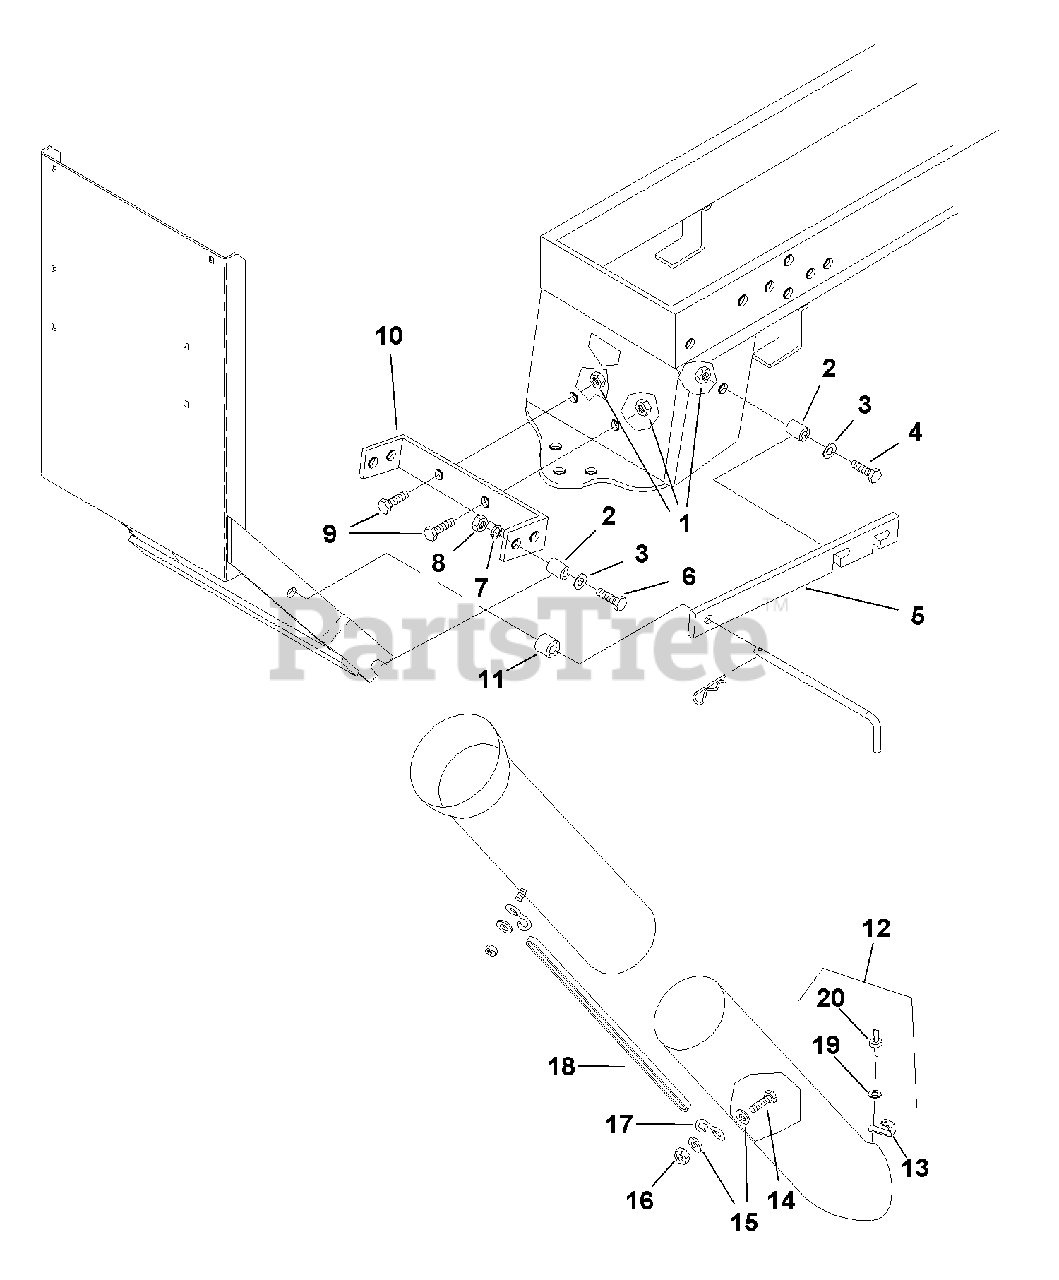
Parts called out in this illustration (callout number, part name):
1	LOCKNUT, Flange, 3/8
3	WASHER, 3/8
4	CAPSCREW, Hex Head, 3/8-16 X 1-3/8
5	SUPPORT ARM
6	CAPSCREW, Hex Head, 3/8-16 x 1-3/4
7	LOCKWASHER, 3/8
8	NUT, 3/8-16
9	CAPSCREW, Hex Head, 3/8-16 x 1
10	SUPPORT
12	TUBE & CLIP ASSEMBLY (44" & 50", LL)
13	CLIP
14	CAPSCREW, Hex Head, 1/4 x 1-1/4
15	WASHER
16	LOCKNUT, 1/4-20
